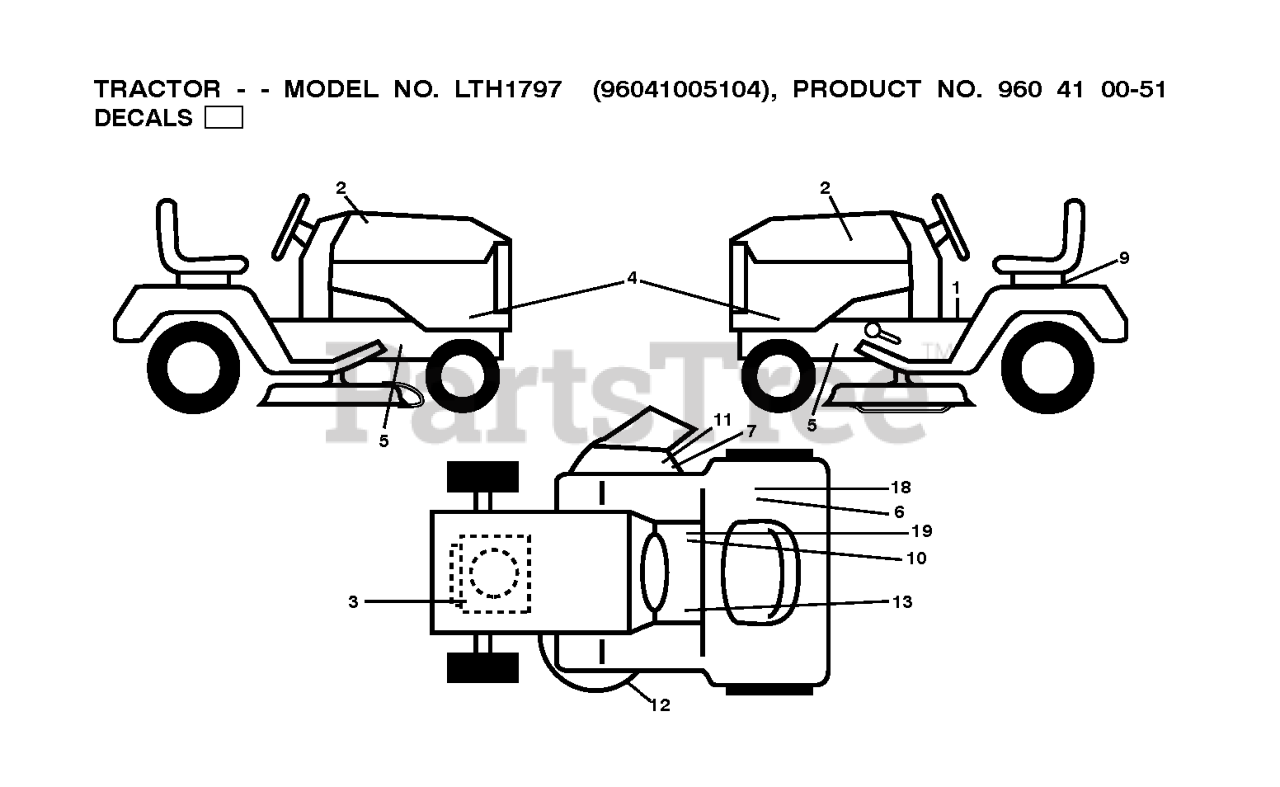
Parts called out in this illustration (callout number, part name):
1	LABEL
2	DECAL.HOOD.LOGO.ORANGE.HUSQVAR
3	DECAL
6	DECAL 80 DBA
7	DECAL, DEFLECT WARNING
9	DECAL BTRY SYMBOLS
10	DECAL PARK BRAKE
11	DECAL.INTERNATIONL.CUTFINGER
12	DECAL.V-BELT.SCHEMATIC.36/38/9
13	DECAL
18	DECAL
19	DECAL
